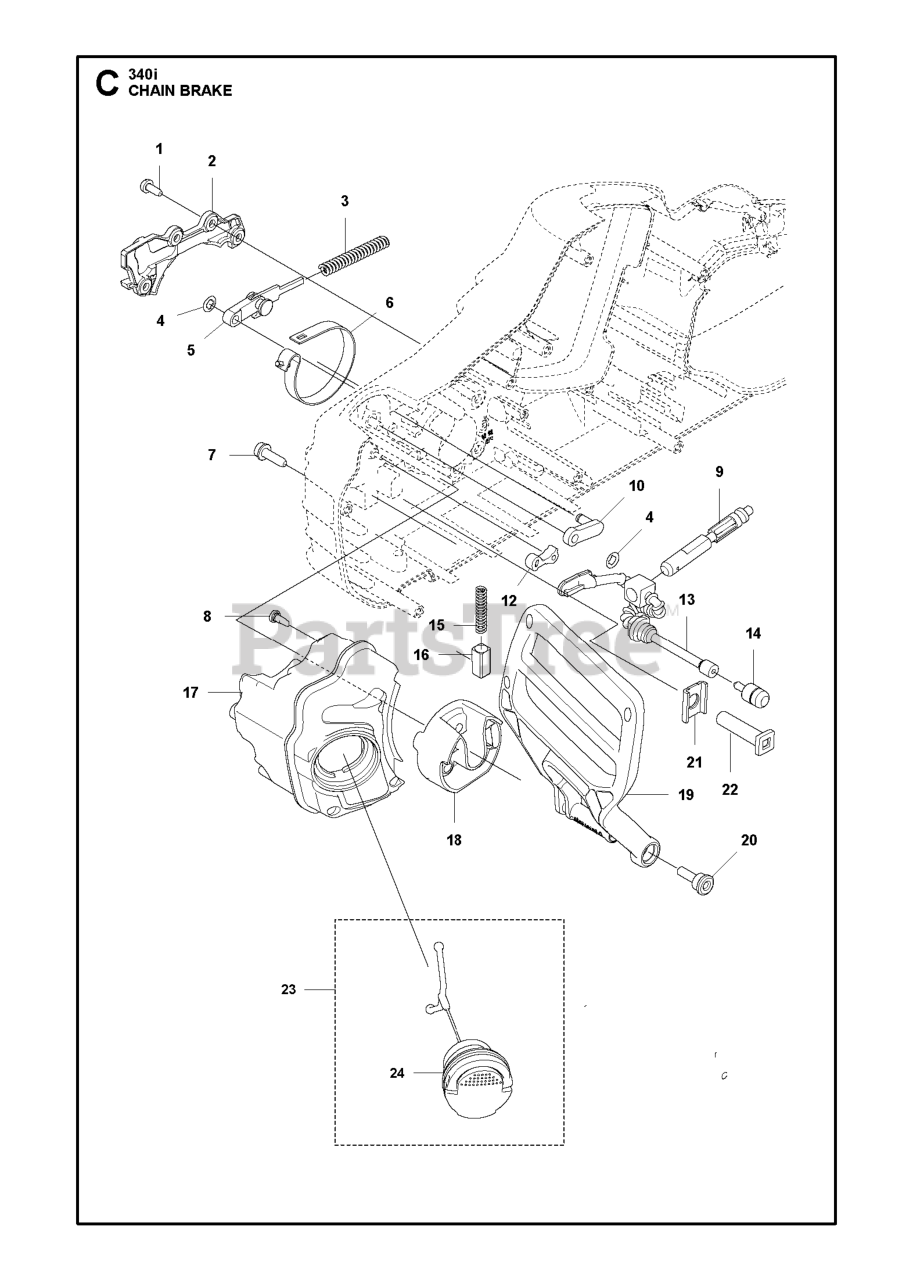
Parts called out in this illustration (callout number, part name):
2	Covers
4	Washers
6	BRAKE BAND
9	PISTON PUMP
10	Drive Links
14	OIL PLUMMET
15	LOCK SPRING
17	Tanks
18	Hand Guard
23	TANK CAP ASSY
